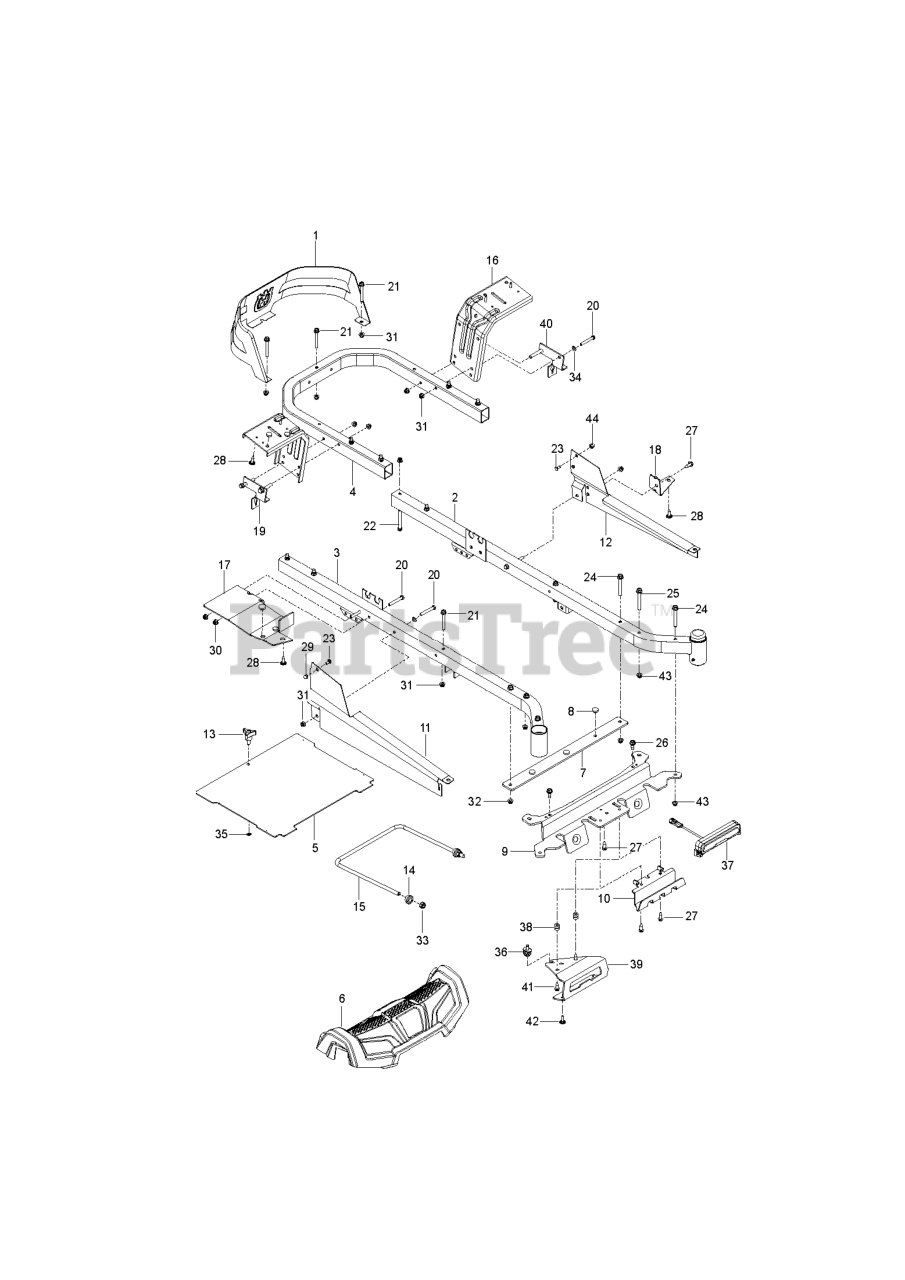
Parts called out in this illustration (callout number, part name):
1	GUARD.ENGINE.HUSQ.RZ.X498
2	FRAME.TUBE.RZ.MAIN.WELD.LH.ORG
3	FRAME.TUBE.RZ.MAIN.WELD.RH.ORG
4	TUBE.PNT.FRAME.RER.HUSQ.23".RZ
5	PLATE, FOOT W/DECALS RZ
5	PLATES
6	COVER.FOOTREST.REFRESH.ASM
7	FOOTREST.PLATE.SUPPORT.X431
8	GROMMET.BUMPER
9	CROSS.PNT.MEMBER.BLK
10	SKID.PLATE.PNT.RZ.REF.SIVER
11	COVER.RAIL.RH.RZ.X668
11	COVER.RAIL.LH.RZ.X668
12	COVER.RAIL.RH.RZ.X668
12	COVER.RAIL.LH.RZ.X668
13	KNOB W/STUD
14	BUSHING SPHERICAL SUSP. FRONT
15	LINK, FRONT SUSP.
16	FENDER.SUPPORT.PNT.X431
17	SUPPORT.PNT.RH.CONSOLE.FRONT
18	SUPPORT.PNT.LH.CONSOLE.FRONT
19	FENDER.SUPPORT.PNT.X431
19	BRKT ROD.BYPASS.EZT.X431
20	BOLT.FIN HEX 5/16-18UNC X2 1/4
21	BOLT HEX
21	BOLT HEX 5/16-18 GR 5
22	BOLT.HEX.FIN.3/8-16 X 3.GR5
23	BOLT.CARRIAGE.5/16-18.7/16
24	HHFS 3/8-16 X 3 GRD 5 ZD
25	BOLT SHOULDER,FLANGED,3/8-16X3
26	BOLT.5/16-18.THRD.ROLL.SHOULDR
27	BOLT.5/16HEX.WHS.HD
28	SCREW.#10 X 0.750.BOS
29	NUT ACORN,FLANGED,5/16-18
29	BOLT.CARRIAGE.5/16-18.7/16
30	NUT LOCK HEX FLANGE 5/16-18
31	5/16-18 NYLOC FLANGE NUT
32	NUT 3/8-16 HEX FLG NYLOC ZD
33	7/16-14 HEX NUT W/NYL RING ZD
34	WASHER
35	WASHER 5/16"
36	SCREW.ADJ.ISOLATOR.BOLT.ASSY
37	LIGHT.ZTR.LED.ASM
38	GROMMET.RUBBER.PUSHIN
39	BRACKET.SKIDPLTE.LED.RFRSHX417
40	BRKT ROD.BYPASS.EZT.X431
41	BOLT.5/16-18X1.25
42	SCREW.#10 X 0.500
43	NUT 3/8-16 HEX FLG NYLOC ZD
44	NUT ACORN,FLANGED,5/16-18
